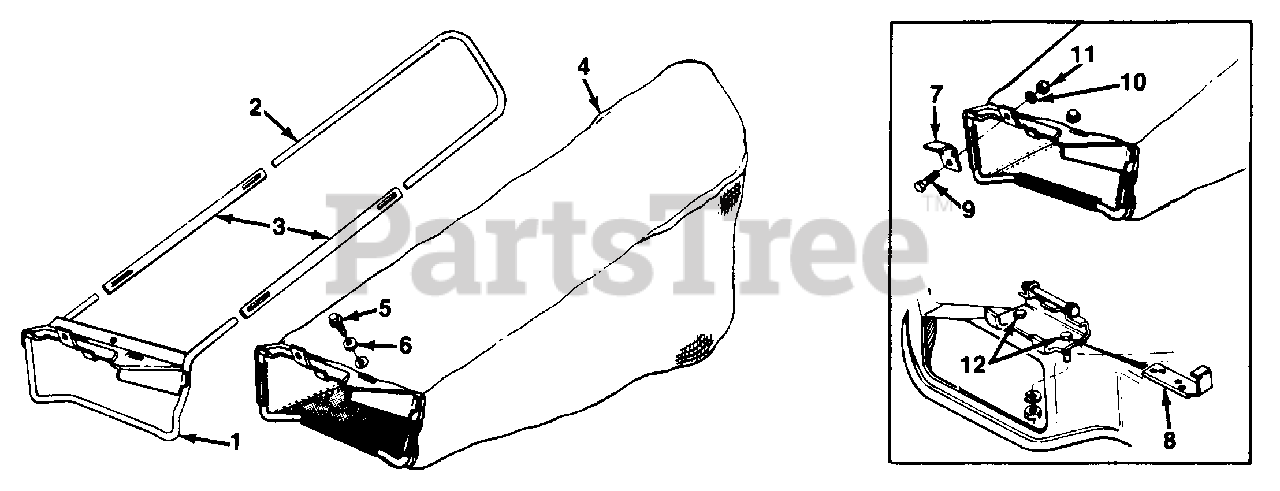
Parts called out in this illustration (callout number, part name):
4	BAG-GRASS
5	SCREW-HEX WASH SF TAPP
6	WASHER-SPRING BELL
7	STOP-DEFLECTOR
8	PLATE-SUPPORT
9	SCREW-HEX 1/4-20 X .50
10	LOCK WASHER 1/4 DIA
11	NUT-HEX 1/4-20
12	SCREW-HEX 1/4-20 C .62
